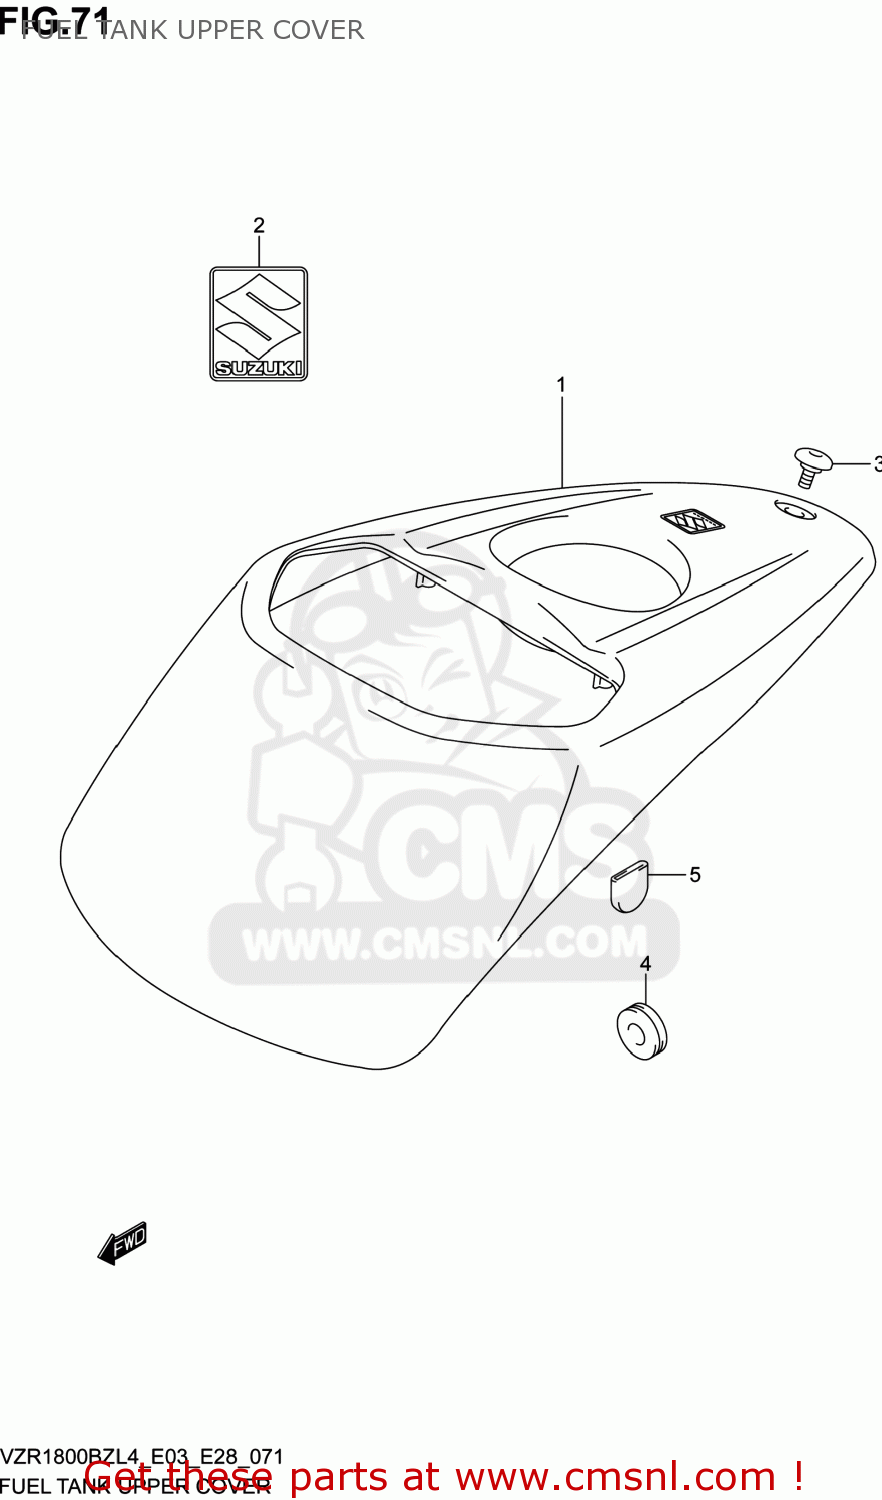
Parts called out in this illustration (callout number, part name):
1	COVER,FUEL TANK UPPER
2	EMBLEM,S
3	SCREW(6X12)
4	CUSHION
5	CUSHION
